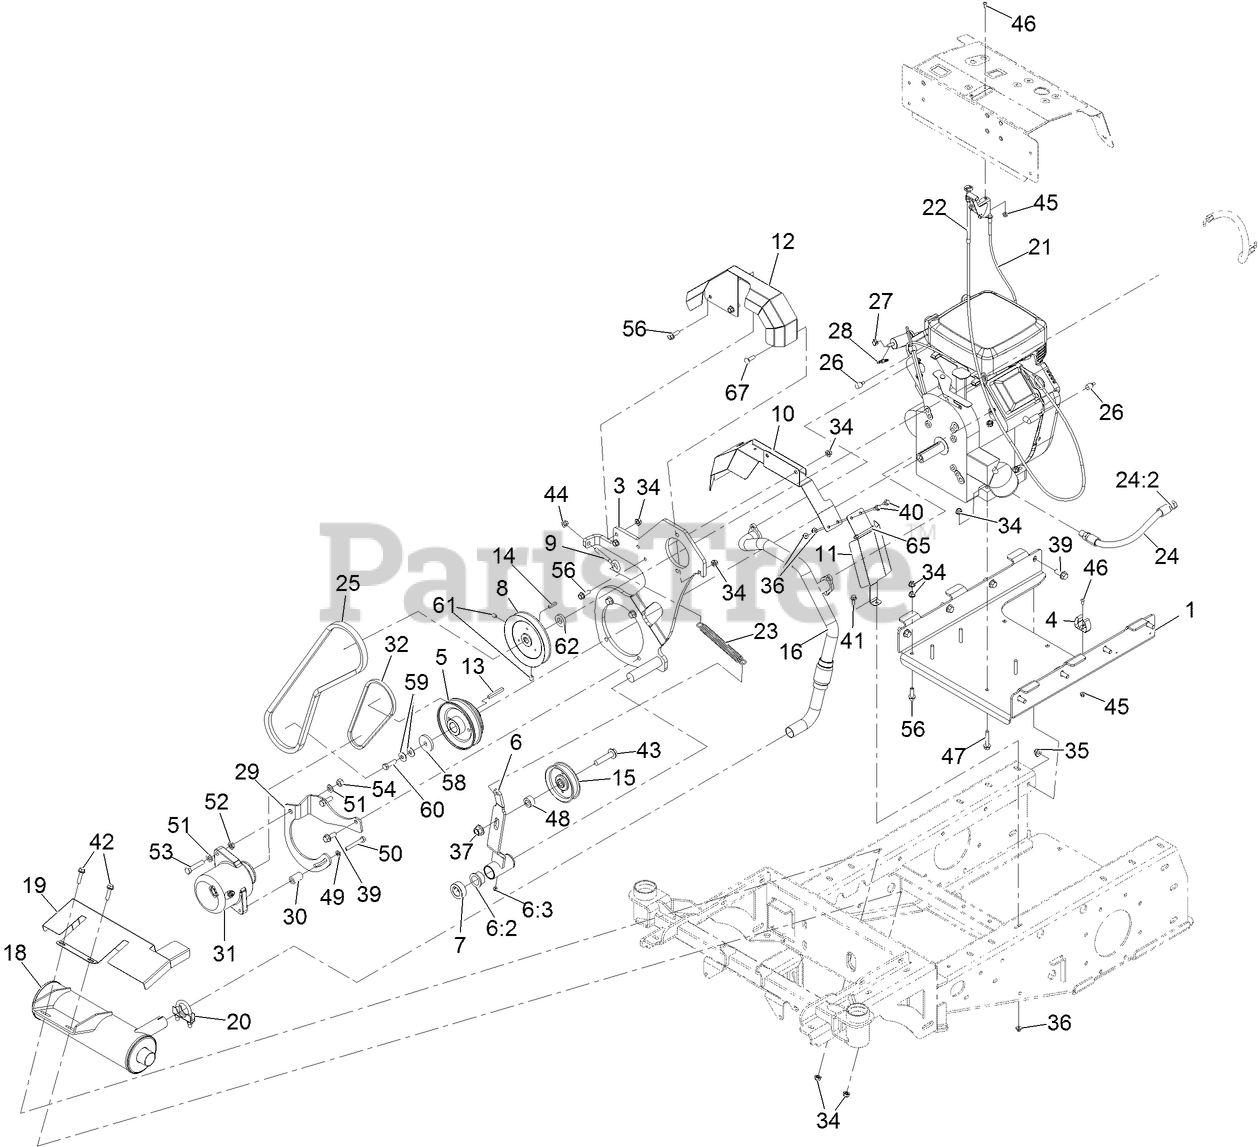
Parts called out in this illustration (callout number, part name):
1	Tray-Engine
3	Bracket-Engine, Pump [black]
4	Holder-Tool, Clip
5	Pulley-Double
6	Arm-Tension, ASM
6:2	BUSHING-FLANGE
6:3	FITTING-GREASE, ZERK
8	PULLEY-DRIVE, PUMP
9	Bolt-Eye
10	Guard, Lower Muffler
11	Guard, Lower Muffler
12	GUARD-PULLEY
15	PULLEY-IDLER, FLAT
16	MANIFOLD-EXHAUST
18	MUFFLER
19	SHIELD-HEAT, MUFFLER
20	Clamp-Muffler
21	CABLE-THROTTLE
22	CABLE-CHOKE
23	SPRING-EXTENSION
24	ASM, Oil Drain Hose W/Plug
26	Tube-Heat Shrink, 1/2
27	CLAMP-HOSE
28	Fitting-STR
29	Bracket-Alternator
30	TUBE-SUPPORT, ALTERNATOR
31	ALTERNATOR
32	Belt-V, 3L240
34	Nut-Hex Flange
35	Nut-Hex Flange
36	Nut-Hex Flange
37	Nut-Lock 1/2-13
39	SCREW-HHF
40	SCREW-HHF
41	Screw-HHF
42	SCREW-HHF
43	Screw-HHF
44	NUT-HF, NI
45	Nut-Hex Flange
46	Screw-HSBH
47	Screw-HHF
49	WASHER-LOCK
50	Screw-HH
51	Washer-Flat
52	Nut-Hex
53	Screw-HH
54	Nut-Lock, NI
56	SCREW-HHF
58	WASHER-PLAIN
59	WASHER-BELLEVILLE
60	Screw-HH
61	Setscrew-HSH
65	TIE-CABLE
67	Bolt,Carriage,5/16-18X1,ST/ST 18-8
